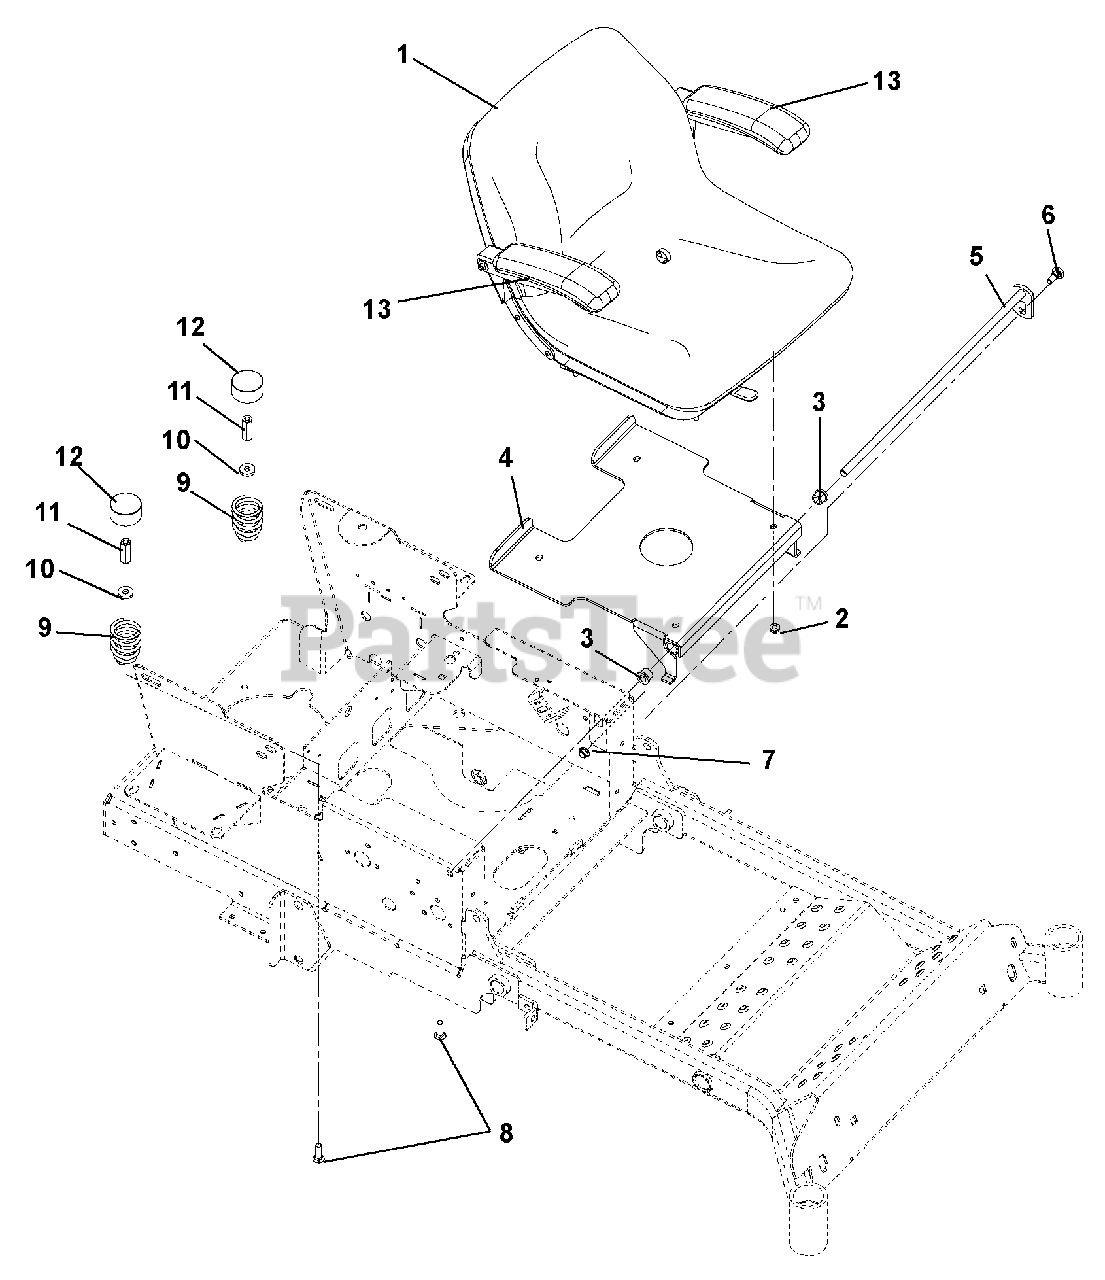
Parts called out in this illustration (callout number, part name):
1	SEAT, MILSCO XB-180
1	SWITCH- SNAP MTG N.O.
2	@NUT-LK-NYL-FLG .31-18 YWZC
3	BSHG, FLG .516X.750X.625X.937
4	WLDMT, SEAT PLATE
5	WMT, SEAT SHAFT
6	BLT,SHLDR EP .38-16X.30 HEX YZ
7	@NUT-SPNLK-FLG .375-16 YWZC
8	@BLT-RDHDSQNK .38-16X1.25 G5YZ
9	SPRING, SEAT
10	WSHR-FL-STL .406X1.00X.188 YWZ
11	NUT COUPLING .375-16X1.75
12	HUB CAP
13	KIT, SEAT ARM RESTS
